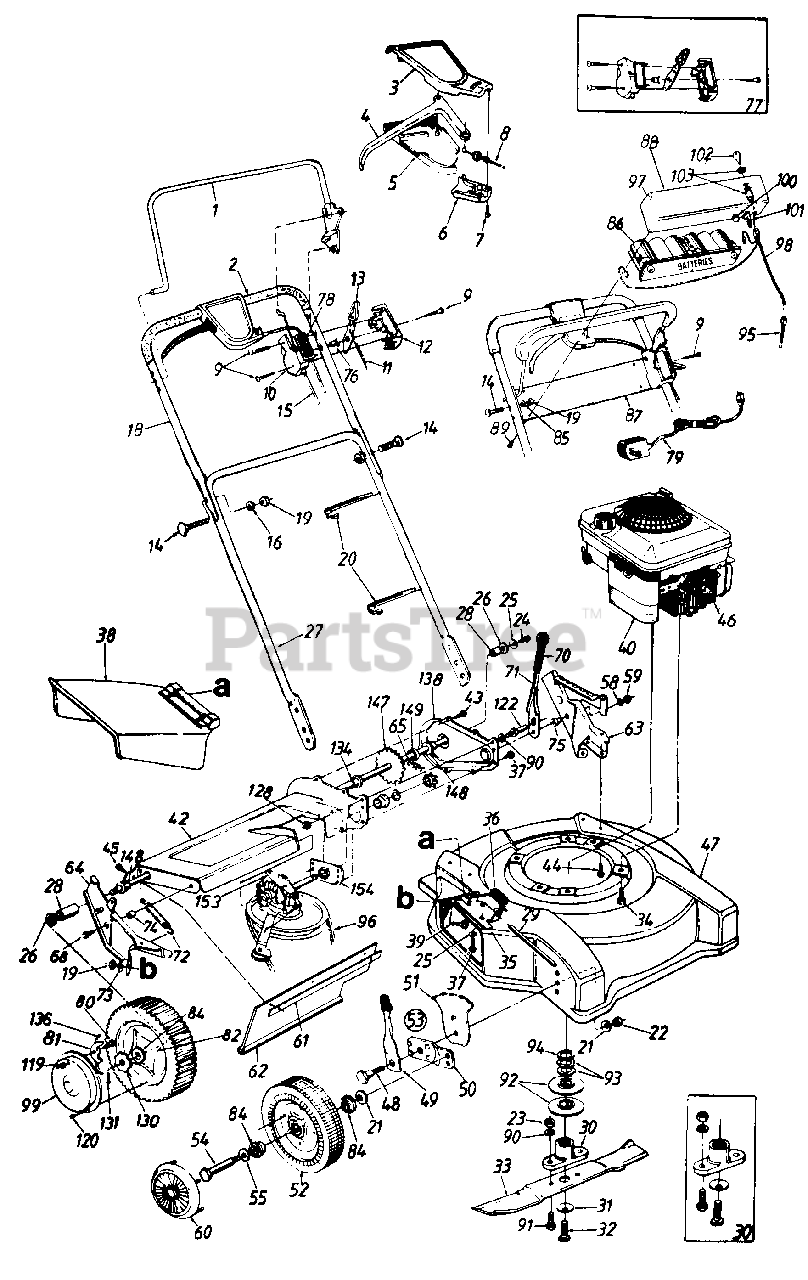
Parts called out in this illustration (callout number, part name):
1	Control Handle Ass'y.
2	Foam Grip
3	Upper-S.P. Control Cover
4	Control Lever
5	Lower-S.P. Control Cover
6	S.P. Control Cover
7	Fl-"C"-Sunk Hd. Tap Scr. #10 x .75" Lg.
8	S.P. Adj. Cable x 48" Lg.
9	Truss Mach. B-Tap Scr. #12 x 1.5" Lg.
10	Clutch Panel Half
11	Throttle Control Wire-53.6"
12	Control Panel Half
13	Throttle Control Lever
14	Curved Carr. Bolt 5/16-18 x 1.38" Lg.
15	Control Cable 43" Lg.
16	L-Wash. 5/16" I.D.
19	Hex Nut 5/16-18 Thd.
20	Cable Tie
21	Bell-Wash. .38" I.D. x .88"
22	Hex Nut 3/8-16 Thd.
23	Hex Nut 3/8-24 Thd.
24	Hex Bolt 1/4-20 x .62" Lg. (Grade 5)
25	Bell-Wash. 1/4" I.D.
26	Fl-Wash. .531" I.D. x .93"
27	Lower Handle
28	Spacer .513" I.D. x .703"
29	Hinge Pin
30	Blade Adapter Kit
31	Bell-Wash..46" I.D.
32	Hex Bolt 7/16-20 x 1.5" Lg.
33	22" Blade
34	Hex L-Wash. Hd. Scr. 3/8-16 x 1.0" Lg.
35	Adapter Plate
36	Torsion Spring
37	Hex Self-Tap Scr. 1/4-20 x .5" Lg.
38	Chute Deflector Ass'y.
39	Carriage Bolt 5/16-18 x .62" Lg.
40	4 H.P. Engine-See Breakdown
44	Hex Wash. Hd. B-Tap Scr. 5/16-1 8
45	Hex AB-Tap Scr. 1/4 x .62"
46	Spark Plug Boot
47	22" Deck Ass'y.
48	Shld. Bolt .5" Dia. x .357
49	Spring Lever Ass'y. w/Knob
51	Height Adj. Plate
52	Wheel Ass'y. Comp.
53	Height Adj. Ass'y. Comp.-R.H.
54	Shld. Bolt .498" Dia. x 1.45"
55	Wave Wash. .53" I.D. x .78"
58	Fl-Wash. .385" I.D. x .87"
59	Hex Patch L-Nut 3/8-24 Thd.
60	Hub Cap
61	Retaining Strip
62	Rear Flap
63	L.H. Handle Wheel Brkt. Ass'y.
64	R.H. Handle Wheel Brkt. Ass'y.
65	#48 Chain .500n Pitch x 30 Links
68	Hex Wash. Hd. Scr. 3/8-16 x 1.0" Lg.
71	Height Adj. Lever
72	Ext. Spring .5" O.D. x 3.8" Lg.
73	Bell-Wash. 5/16" I.D.
74	Spacer .383" I.D. x .503"
75	Shld. Spacer .5" Dia.
76	Control Disc Pin
77	Control Housing Comp.
78	Control Label-Throttle
79	Battery Charger
80	Shld. Scr. .342" Dia. x .268"
81	Pawl
82	Wheel Ass'y. Comp.
84	Ball Bearing 1/2" I.D.
85	Bell-Wash. .345" I.D. x .88"
86	1 2-Volt Battery
87	Lower Battery Tray
88	Instruction Label
89	Hex AB-Tap Scr. 1" Lg.
90	L-Wash. 3/8" I.D.
91	Hex Bolt 3/8-24 x 1.0" Lg.
92	Serrated Pulley Half
93	Wave Washer 1.005" I.D.
94	Serrated Washer 1.0" I.D.
95	Ext. Harness
96	"V"-Belt
97	Upper Battery Tray
98	Wire Harness
99	Rear Hub Cap
100	Fuse Holder
101	Plug
102	Key
103	Key Switch
119	Hex Ins. L-Nut 1/4-20 Thd.
120	Pan Hd. Tap Scr. #12 x .5
122	Shld. Pin 3/8-24 x 1.43" Lg.
128	Hex Jam Nut 3/8-24 Thd.
130	Ratchet Wheel 1.62" O.D.
131	Cotter Pin 1/8" Dia.
134	Hex Flange Bearing
136	Spring-Nylon
148	Hex Flange Bearing
149	Fl-Wash. .531" I.D. x .93"
153	Transmission Comp.
